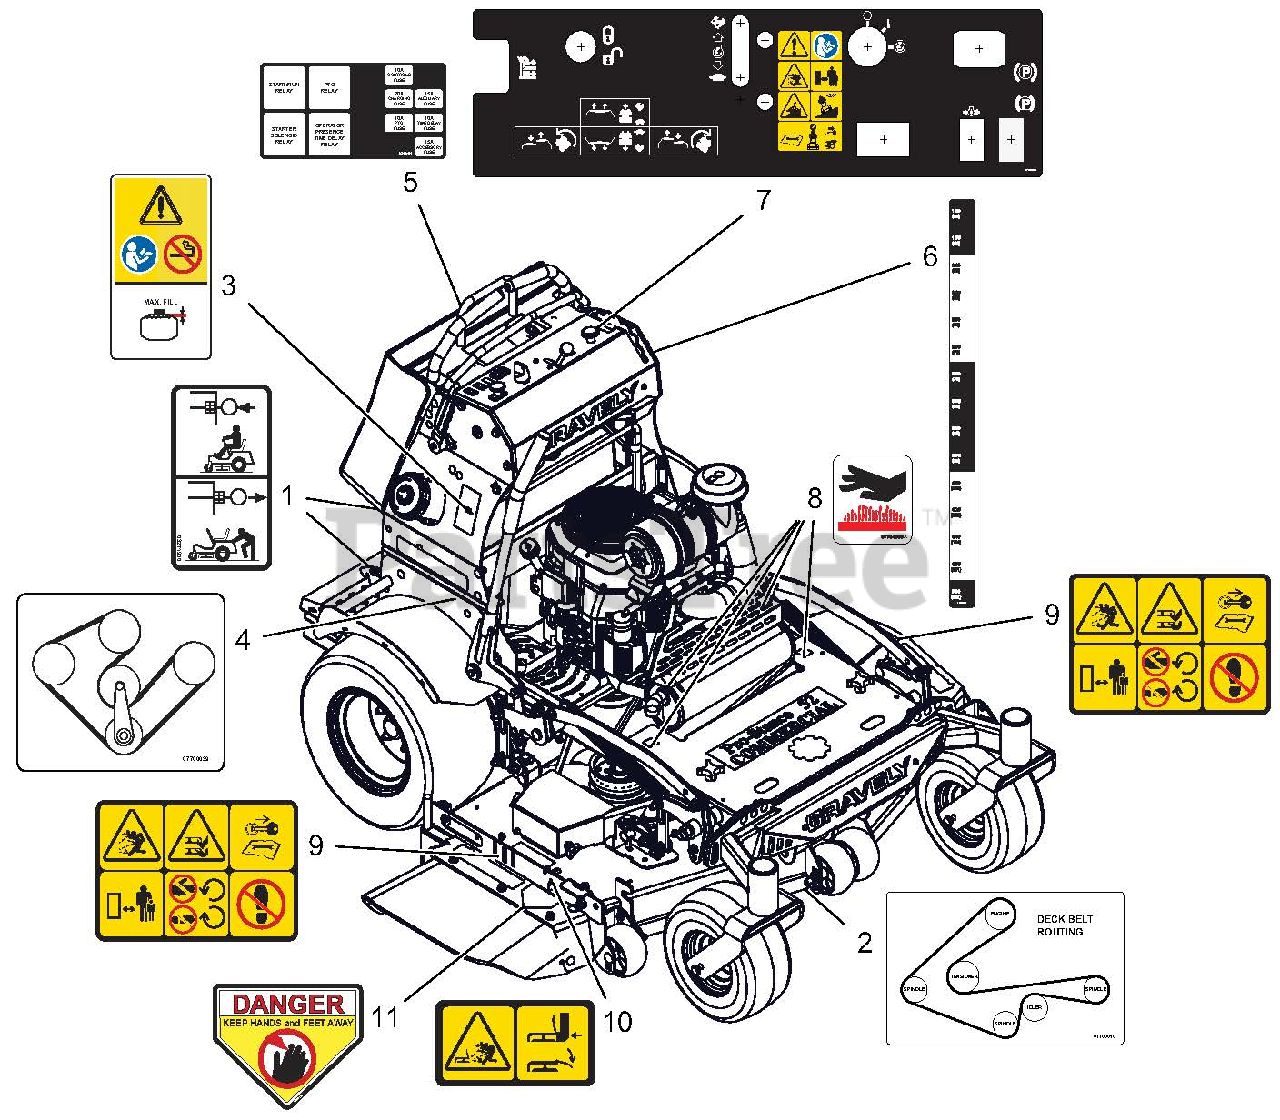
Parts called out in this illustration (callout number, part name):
1	DECAL, TRANSMISSION DISCONNECT
2	DECAL, BELT ROUTING 48/52 REV
3	DECAL, FUEL Warning
4	DECAL, HYDRO BELT
5	DECAL, FUSE BLOCK
6	DECAL, HEIGHT OF CUT - PROSTANCE
7	DECAL, CONTROL PANEL EFI
8	DECAL HOT SURFACE
9	DECAL, SAFETY - MOWER DECK
10	DECAL, SAFETY - DECK GUARDING
11	DECAL, DANGER
